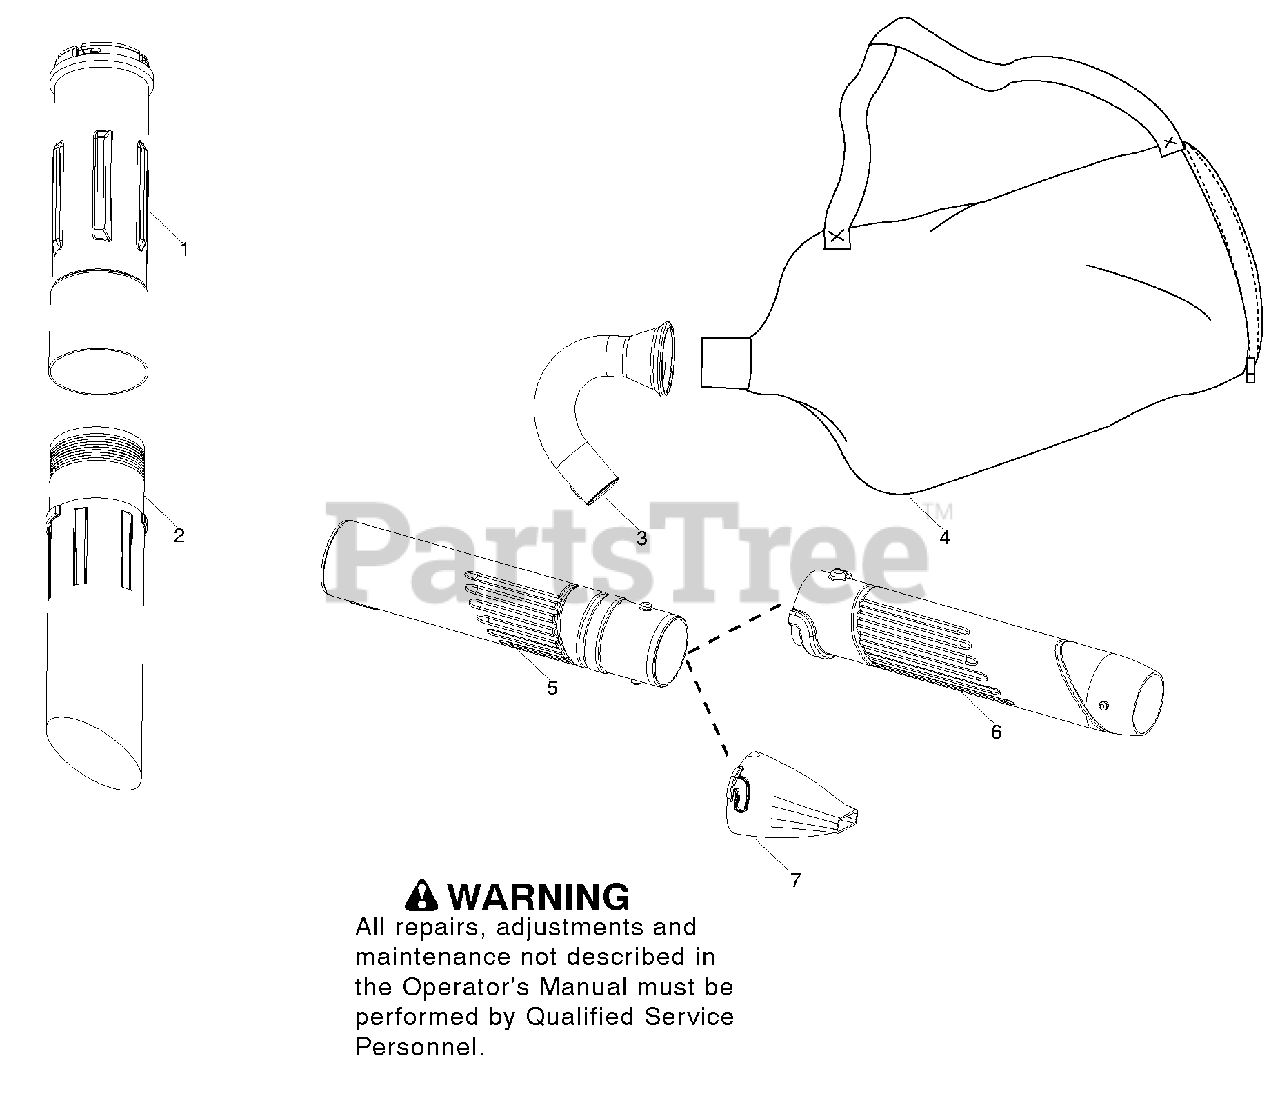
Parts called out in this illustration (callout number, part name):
1	Tube - Upper Vac
2	Tube - Lower Vac
3	Tube - J
4	Assy - Vac Bag
5	Tube - Upper Blower
6	Tube - Lower Blower
7	Nozzle - High Speed
